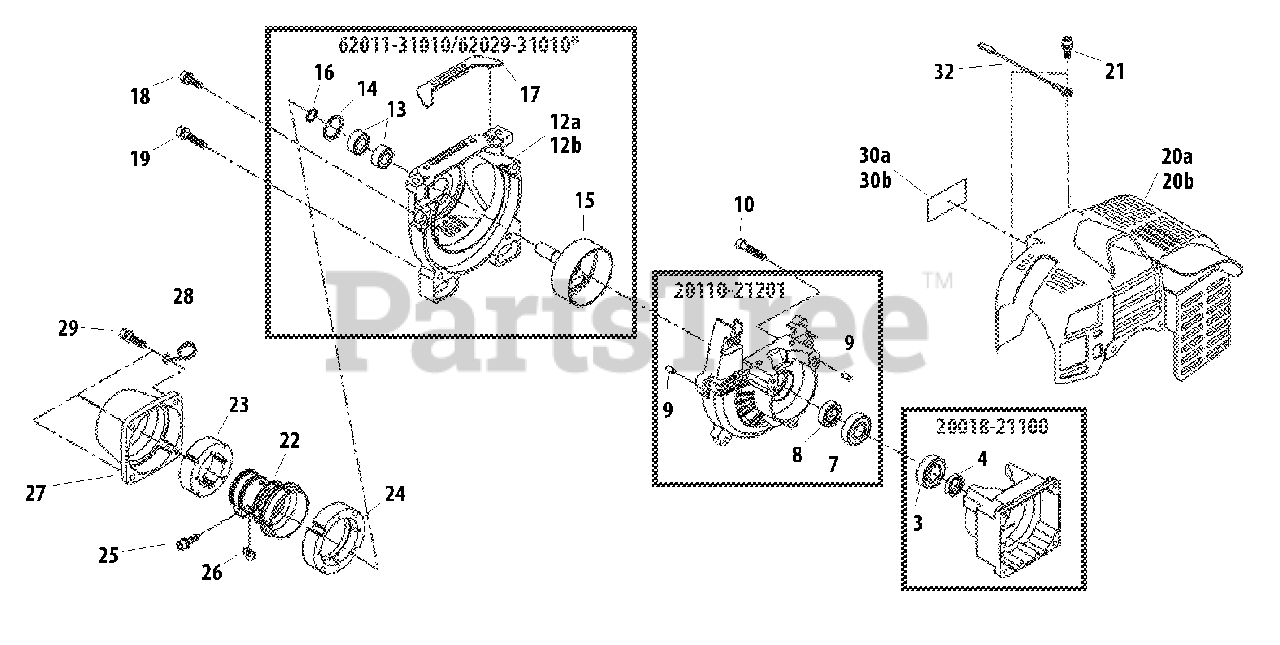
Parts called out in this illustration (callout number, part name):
3	BEARING, BALL 6001 C3
4	SEAL, OIL 12
7	BEARING, BALL 6001 C3
8	SEAL, OIL 12
9	PIN, LOCATING Ø4×8
10	BOLT 5×25
12A	COVER, FAN (RED)
12B	COVER, FAN (BLUE)
13	BEARING, BALL 6000DDU
14	RING, SNAP Ø26
15	DRUM, CLUTCH
16	RING, SNAP WR10
18	BOLT M5×16
19	BOLT M5×25
20A	COVER, ENGINE - RED
20B	COVER, ENGINE - BLUE
21	BOLT M5×16
22	JOINT
23	CUSHION, FRONT
24	HOLDER, REAR CUSHION
25	BOLT M5×25
26	D-WASHER
27	COVER, AV CUSHION (RED)
28	HOLDER, THROTTLE CABLE
29	BOLT M5×20
30A	LABEL, TRADE (RED)
30B	LABEL - MODEL
32	LEAD - GROUND
20018-21100	CRANKCASE ASSY, S
20110-21201	CRANKCASE ASSY, M
62011-31010	FAN CASE ASSY - RED
62029-31010	COVER, FAN (BLUE)
